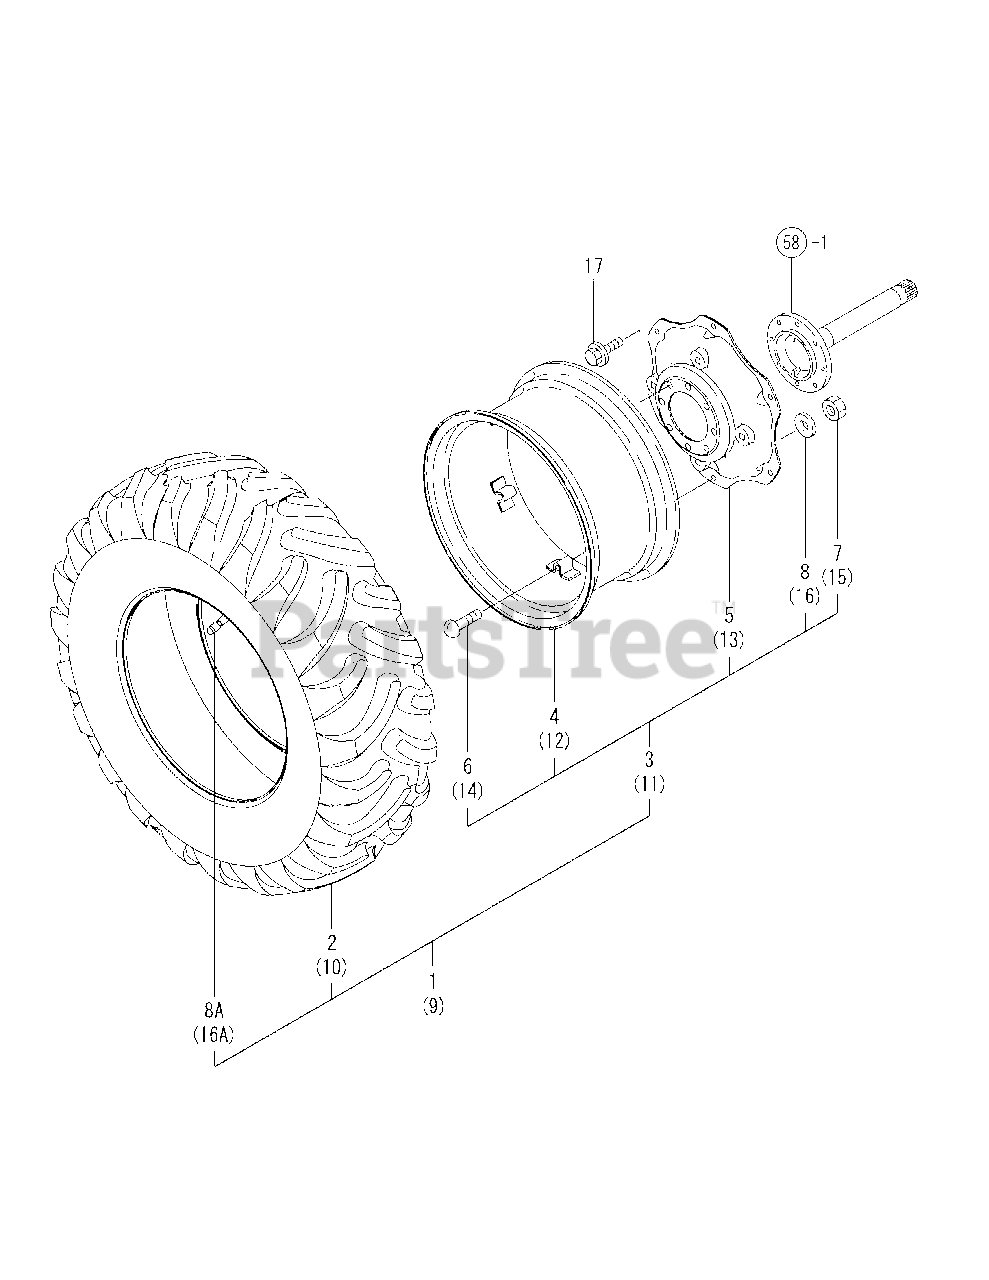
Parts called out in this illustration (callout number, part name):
1	R1 TIRE KIT,WHEEL REAR LEFT
2	TIRE, R1 14.9X24
9	R1 TIRE KIT, WHEEL REAR RIGHT
10	TIRE, R1 14.9X24
